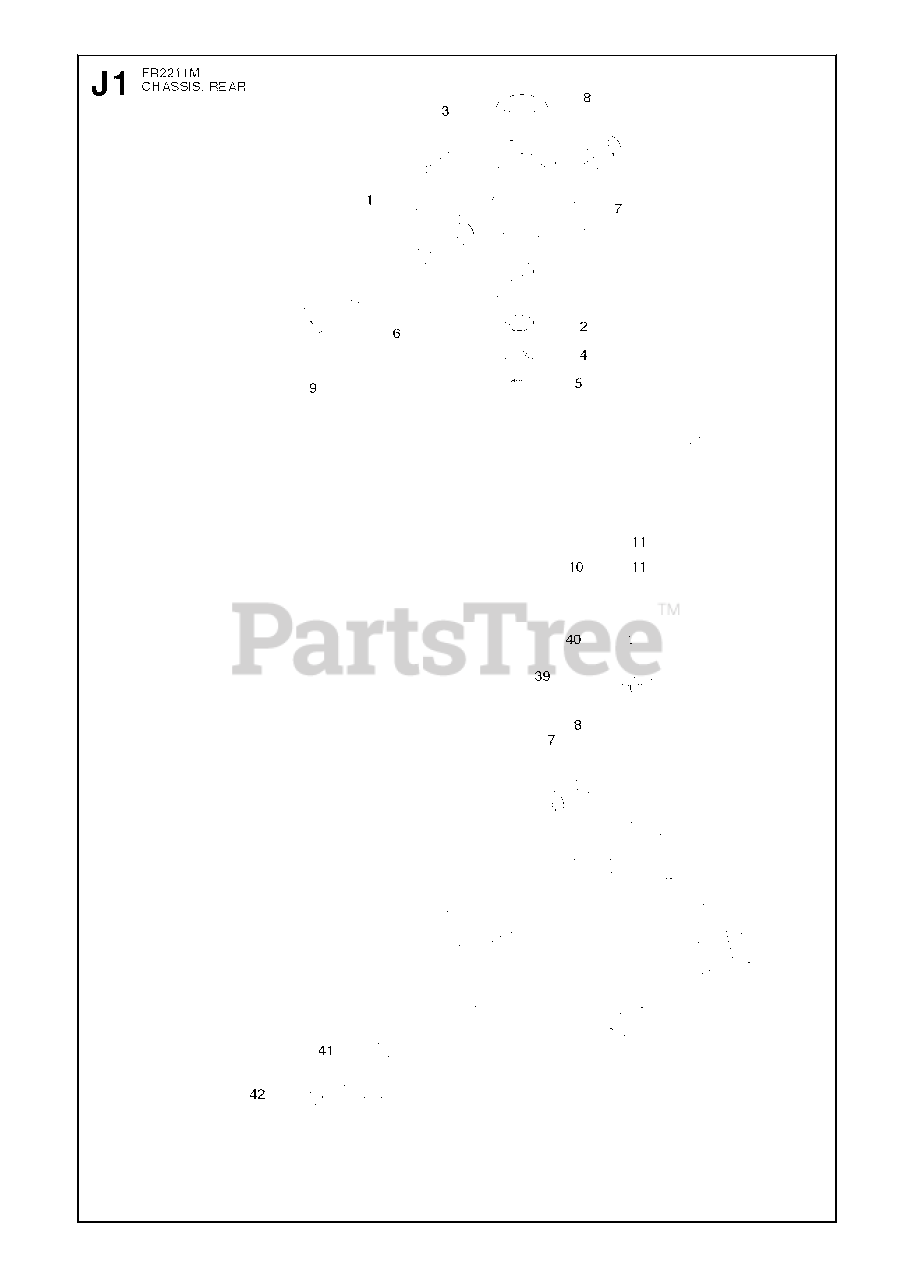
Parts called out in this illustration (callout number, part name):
2	BALL BEARING 6005-2RS
3	BALL BEARING 6010 2RS1
4	CIRCLIP SGH 47
5	RETAINING RING SGA 25
7	RETAINING RING SGA 25
11	BUSHING
41	DRAW RING
42	SCREW M10X25
